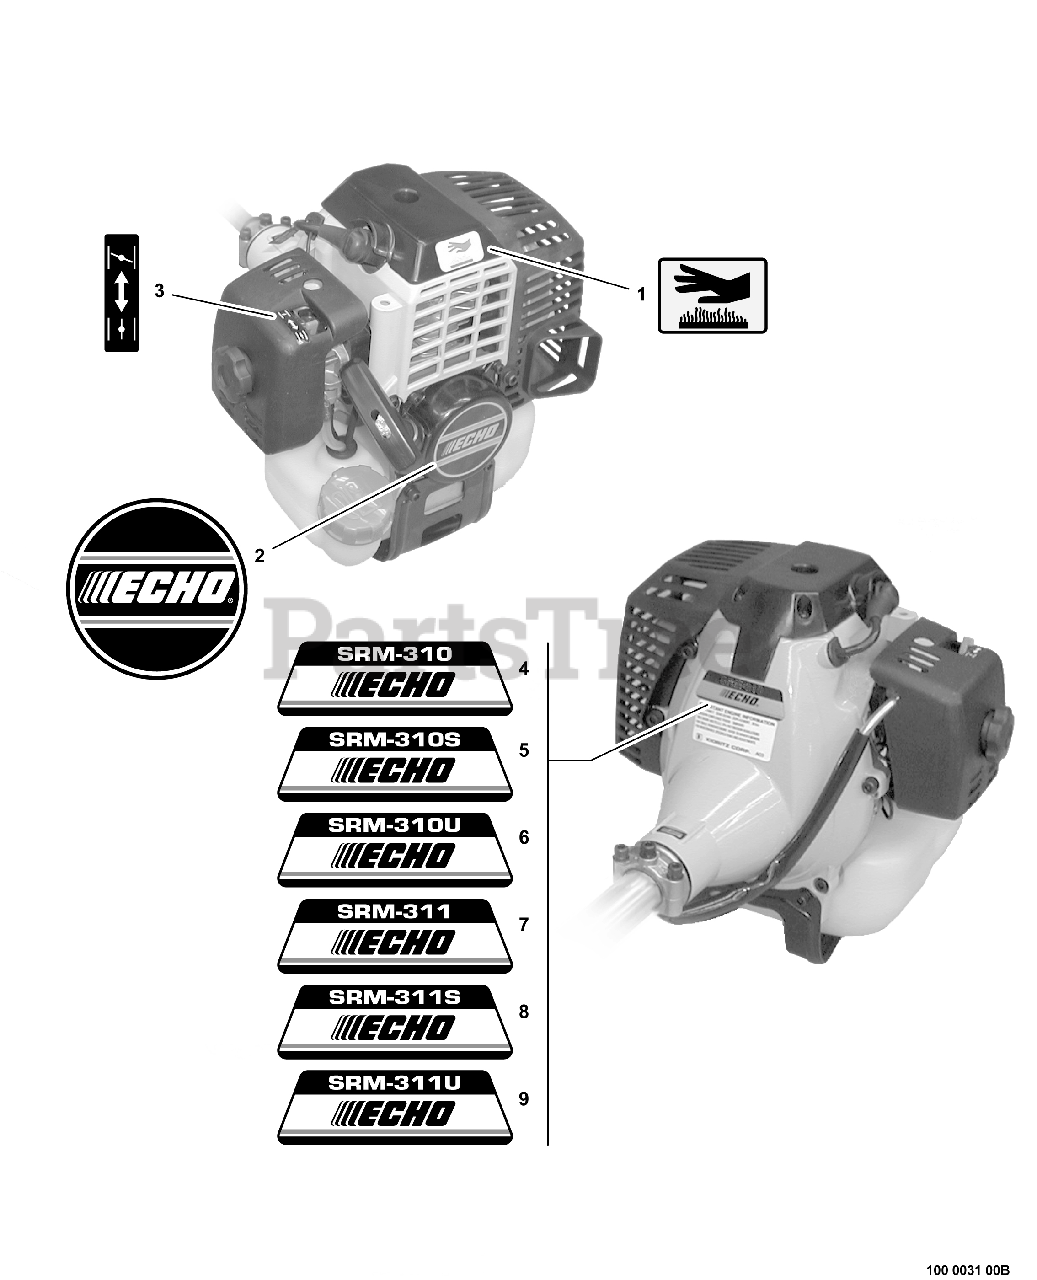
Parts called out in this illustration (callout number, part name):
1	LABEL - HOT SURFACE
2	LABEL - ECHO
3	LABEL - CHOKE
4	LABEL - MODEL SRM-310
5	LABEL - MODEL SRM-3110S
6	LABEL - MODEL SRM-310U
7	LABEL - MODEL SRM-311
8	LABEL - MODEL SRM-311S
9	LABEL - MODEL SRM-311U
